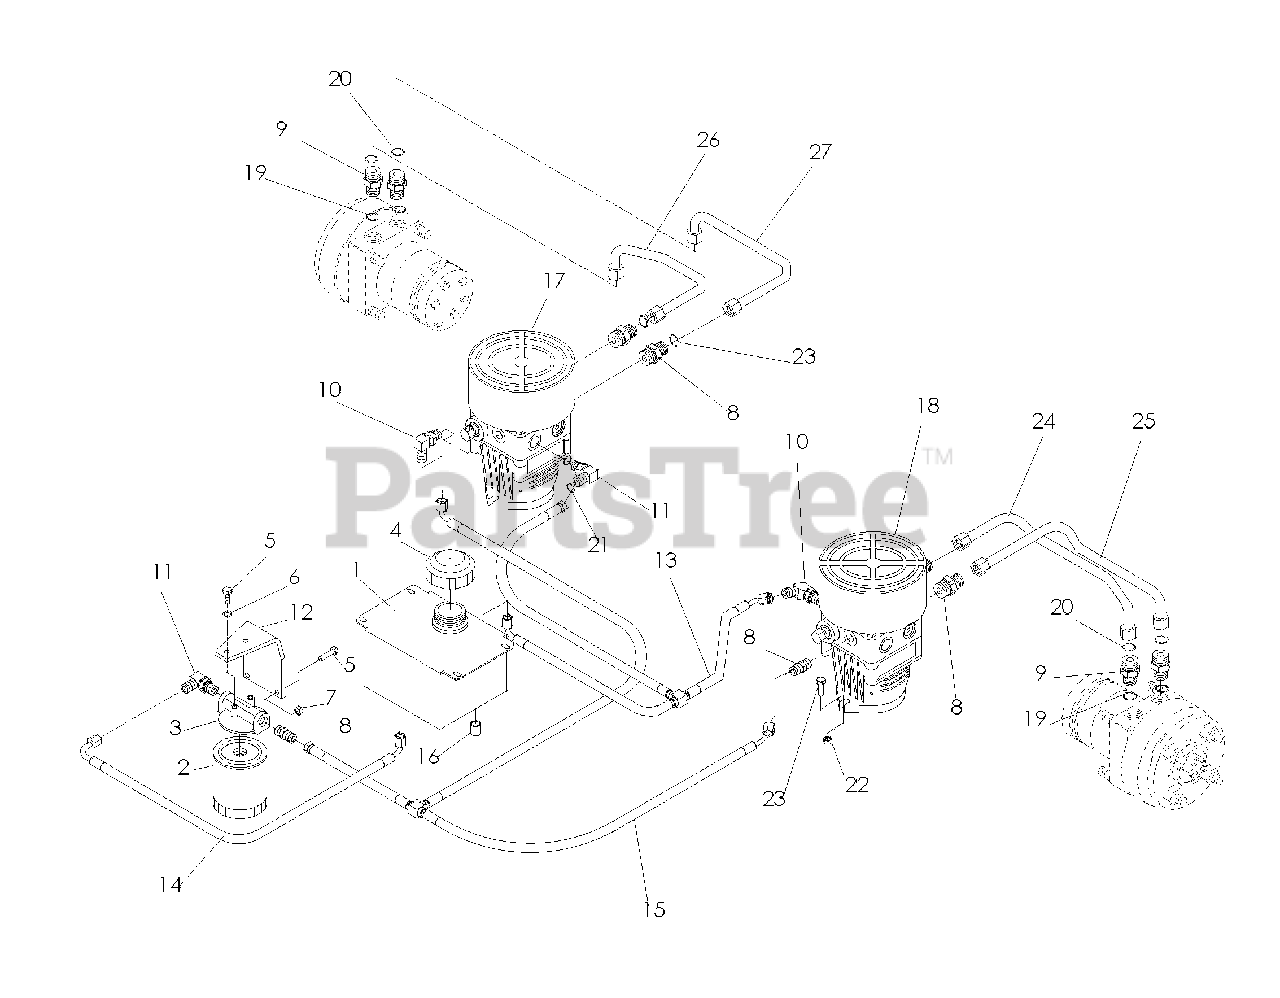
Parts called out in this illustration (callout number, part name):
3	FILTER HEAD
4	CAP, HYDRAULIC
5	HCS 1/4- 20 x 3/4
6	LOCKWASHER 1/4
7	NUT 1/4-20 HEX NYLOC
8	HYDRAULIC FITTING
9	STRAIGHT FITTING
12	BRACKET, FILTER
13	‘T’ ASSEMBLY, RETURN
14	HOSE
15	‘T’ ASSEMBLY, SUPPLY
17	PUMP W/FANS, 10CC, RT
18	PUMP W/FANS, 10CC, LT
22	NUT 3/8-16 CENTERLOCK
23	HCS 3/8-16 x 1 WHIZLK
24	HYDRAULIC LINE
25	HYDRAULIC LINE
26	HYDRAULIC LINE
27	HYDRAULIC LINE
